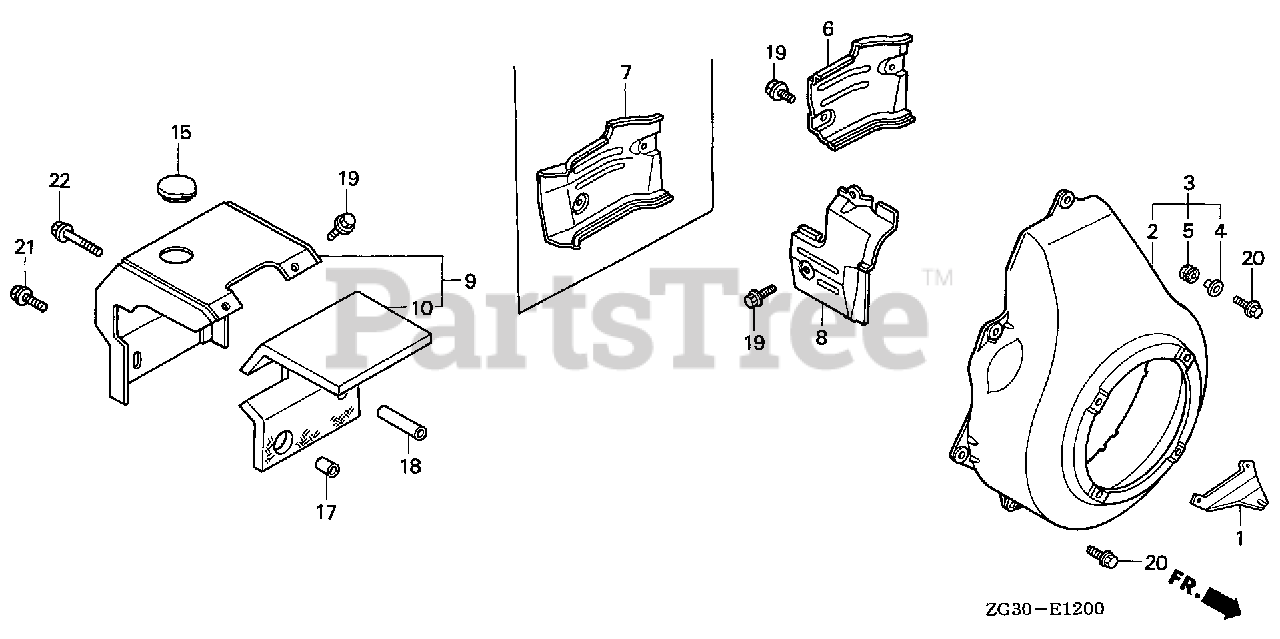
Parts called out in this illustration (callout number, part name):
2	COVER, FAN *NH116M* (URBAN SILVER METALLIC)
6	SHROUD (A)
8	SHROUD (B)
19	BOLT, FLANGE (6X12)
20	BOLT, FLANGE (6X12)
